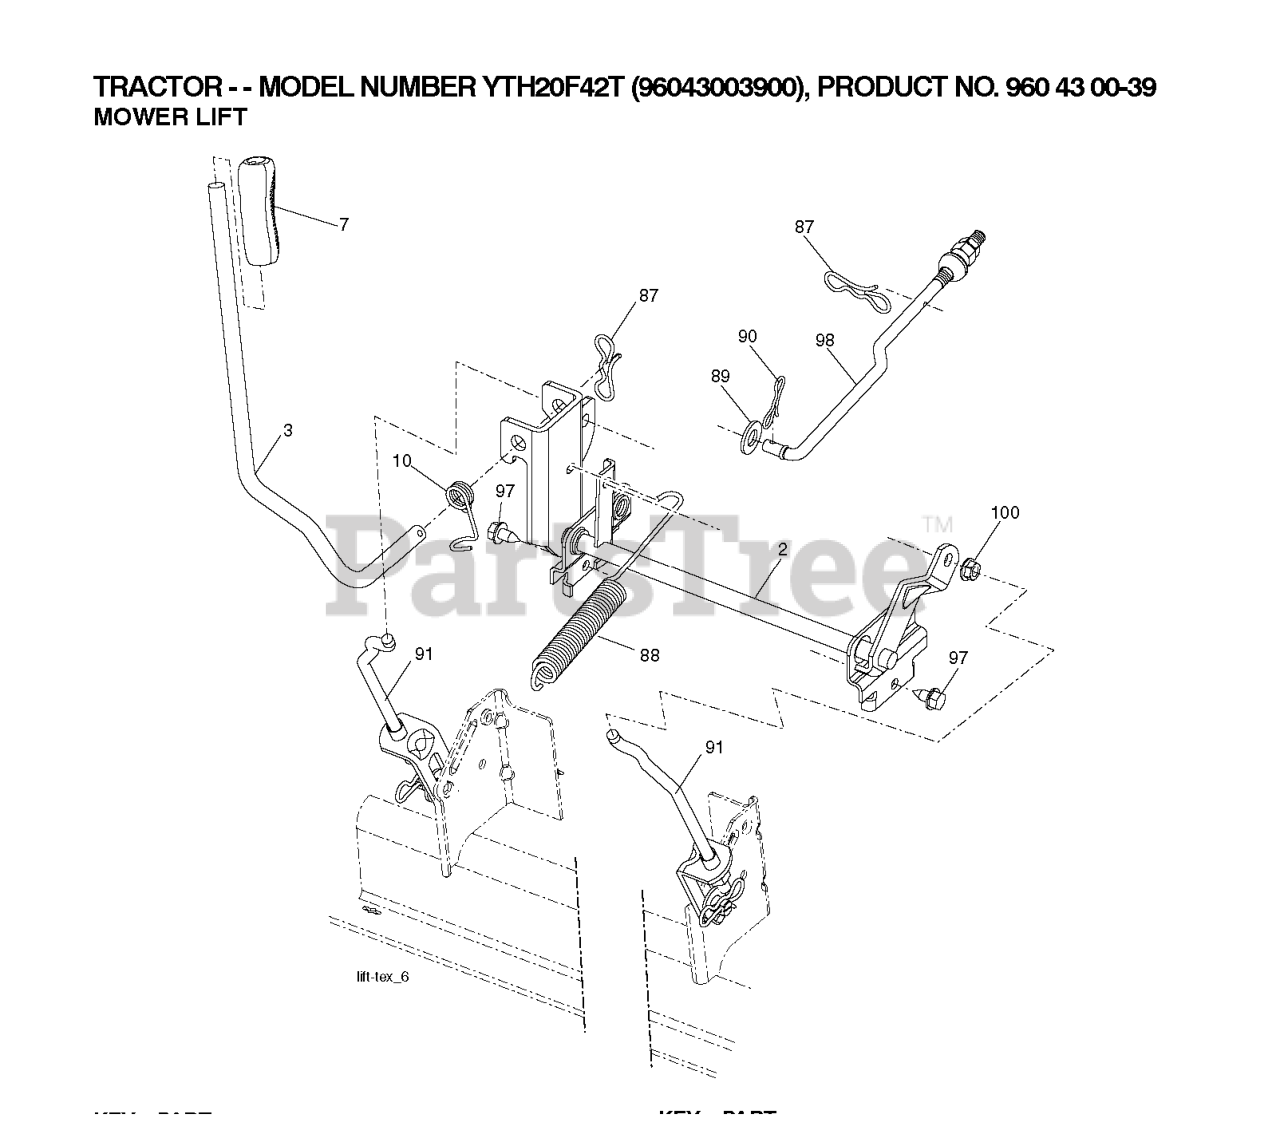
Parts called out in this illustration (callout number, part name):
2	SHAFT.ASM.LIFT.CROSS.H
3	LEVER.LIFT.HANDLE.LT
7	GRIP.HANDLE.LIFT.PVC.BLACK
10	SPRING.TORSION.LIFT.HANDLE
87	PIN.COTTER.7/16.BOW TI.
88	SPRING.LIFT.ASSIST
89	WASHER.CLEAR.ZINC
90	PIN.COTTER.5/16.BOW TI
91	LINK.ASM.LIFT.REAR
97	SCREW, 3/8-16X3/4
98	LINK.ASM.SUSP.FRONT.MW
100	LOCKNUT
